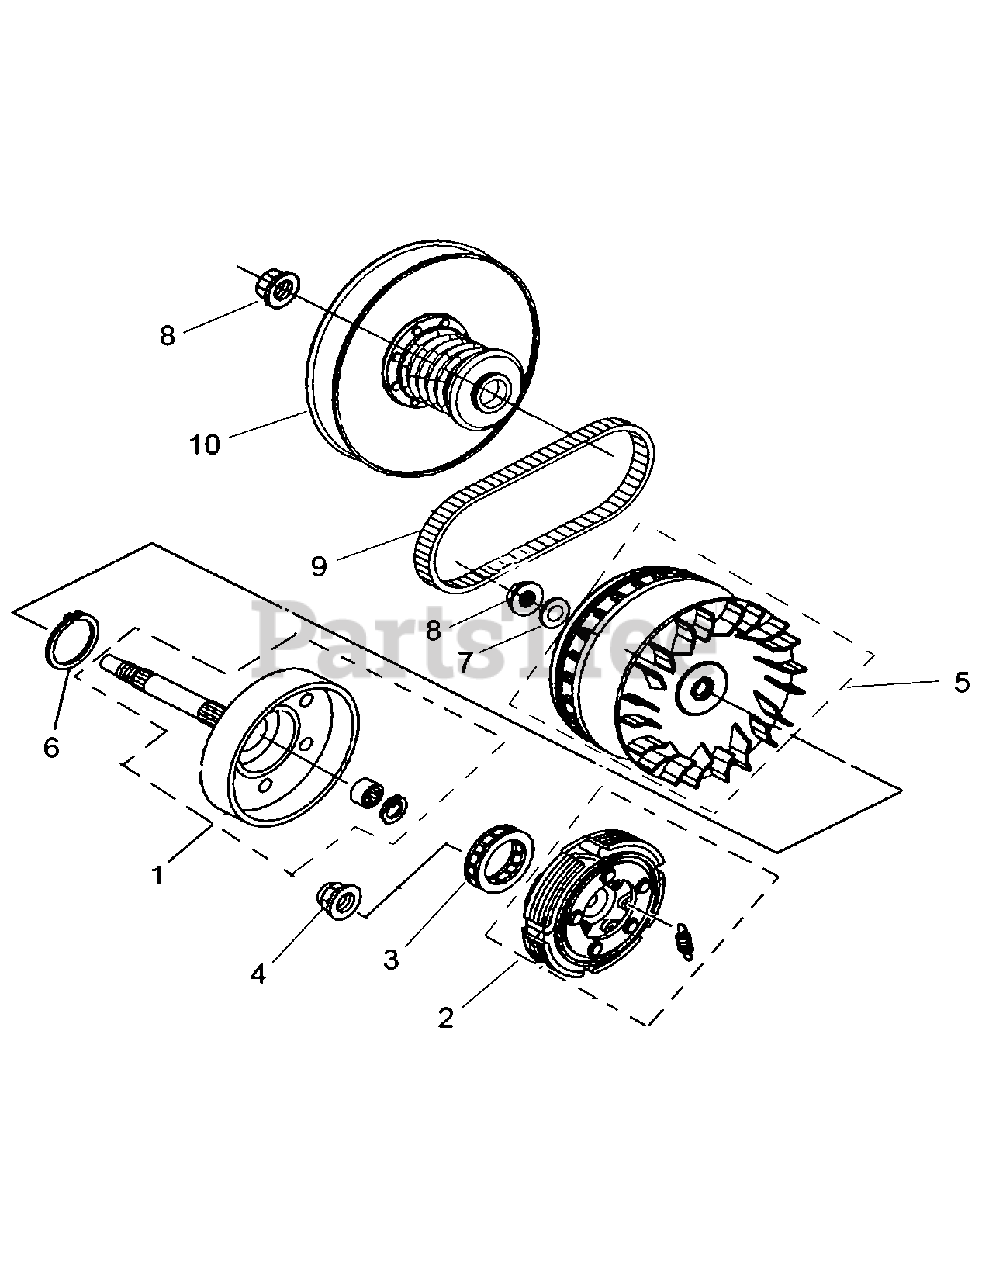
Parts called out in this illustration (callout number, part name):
1	Cover-Outer Clutch
2	Clutch-Complete
3	One Way Machine-Co
5	Cvt Clutch-Driver
9	Belt
10	Cvt Hypo Clutch-Dr
